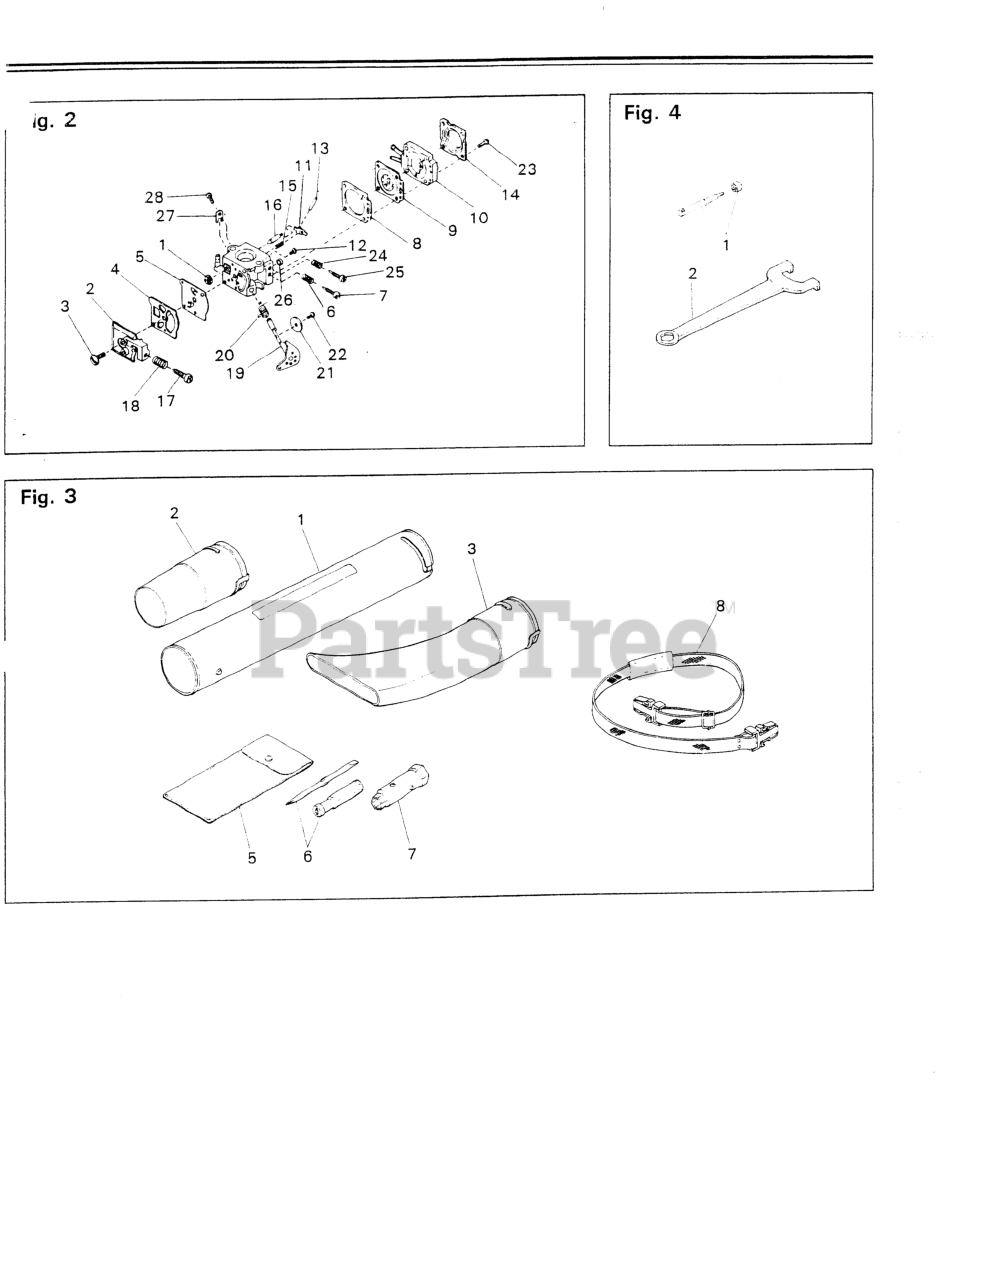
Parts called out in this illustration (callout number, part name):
2-2	COVER, PUMP
2-4	GASKET, PUMP
2-5	KIT ONLY
2-7	NEEDLE, IDLE
2-8	KIT ONLY
2-9	DIAPHRAGM (USE 4810-81260)
2-10	BODY ASSEMBLY
2-11	LEVER
2-13	PIN, METERING LEVER
2-14	COVER
2-15	KIT ONLY
2-16	KIT ONLY
2-18	SPRING, IDLE
2-23	SCREW (USE 1480-81520)
2-28	SCREW ASSEMBLY
3-2	NOZZLE JET
3-6	SCREWDRIVER
4-1	ROD ASSEMBLY (TOOL) (NLA)
4-2	SPANNER (TOOL)
NI	TOOL SET
